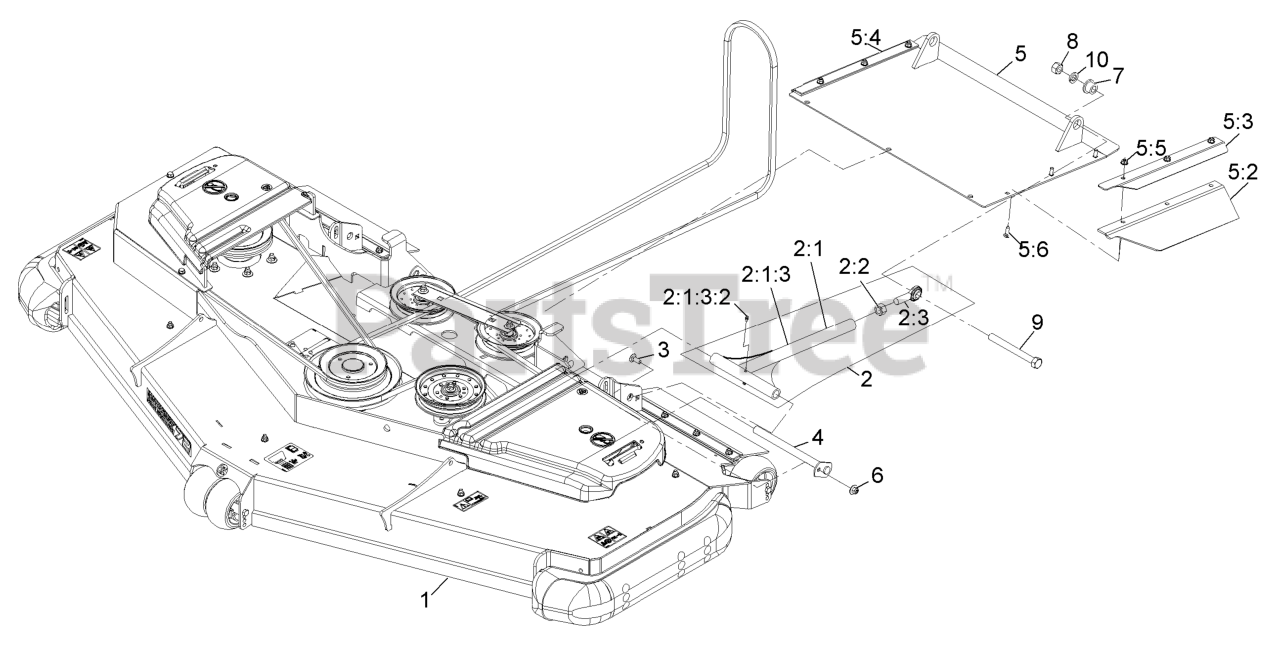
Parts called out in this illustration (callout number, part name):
1	ASM-Deck Complete Rd72
2	ASM,DECK STRUT XS 72
2:1	WLD,DECK STRUT
2:1:3	Tube And Zerk ASM
2:2	NUT-HEX
2:3	BALLJOINT-SPHERICAL
3	BOLT-CARR
4	PIN-STRUT
5	ASM-DISCHARGE TUNNEL RD72
5:2	FLAP-RD TUNNEL SIDE
5:3	BRKT-RD TUNNEL FLAP LH
5:4	BRKT-RD TUNNEL FLAP RH
5:5	NUT-HF, NI
5:6	SCREW-CARR
6	Nut-Nyloc 3/8-16 Flg
7	BUSHING-FLANGE
8	NUT-HEX
10	WASHER-LOCK
